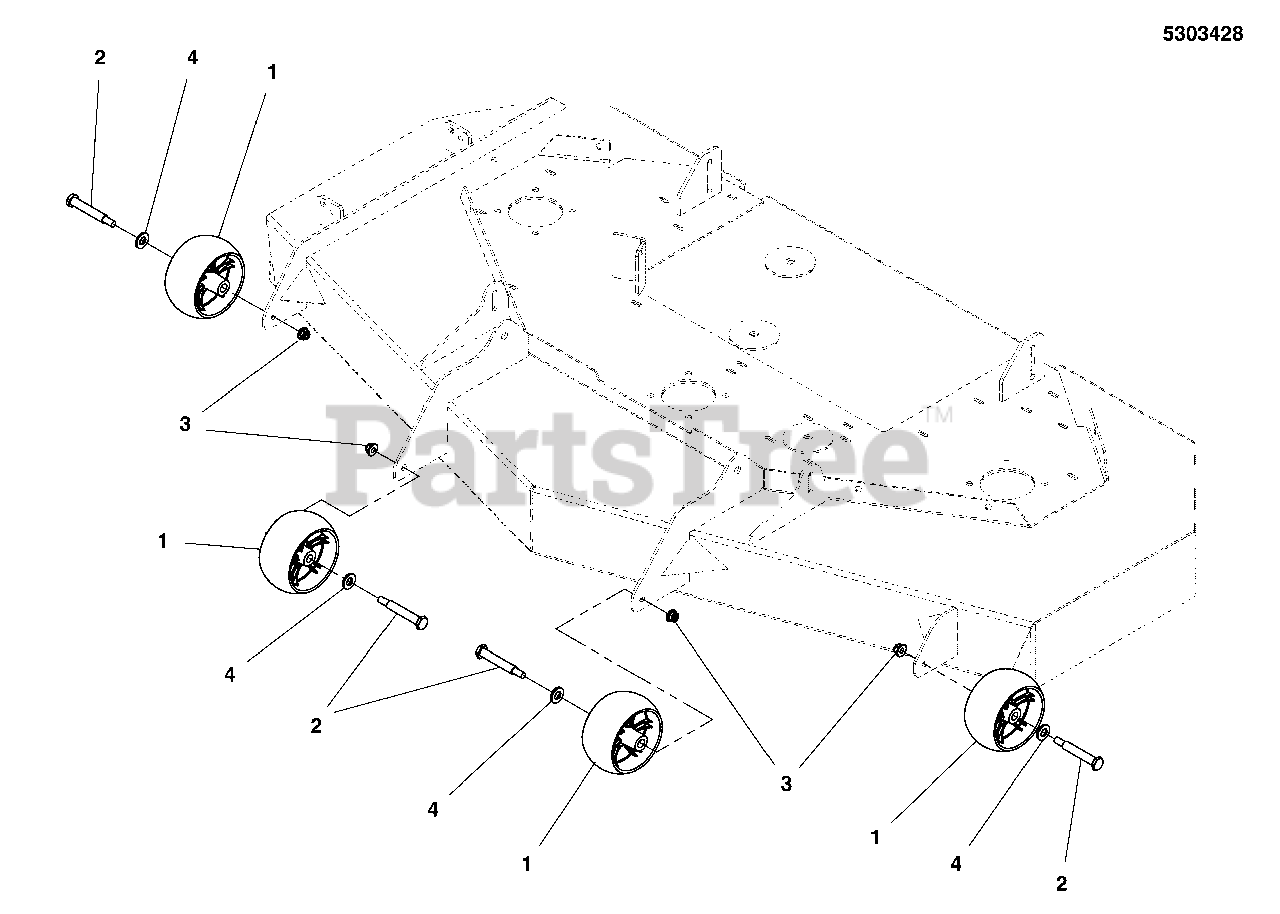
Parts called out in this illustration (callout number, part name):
1	WHEEL, GAUGE BLACK POLY 5" DIA
2	BOLT, SHLDR 3/8-16X3.41 .750 THRD
3	NUT, Hex Flange, Nylock, 3/8-16
4	WASHER, 1/2
